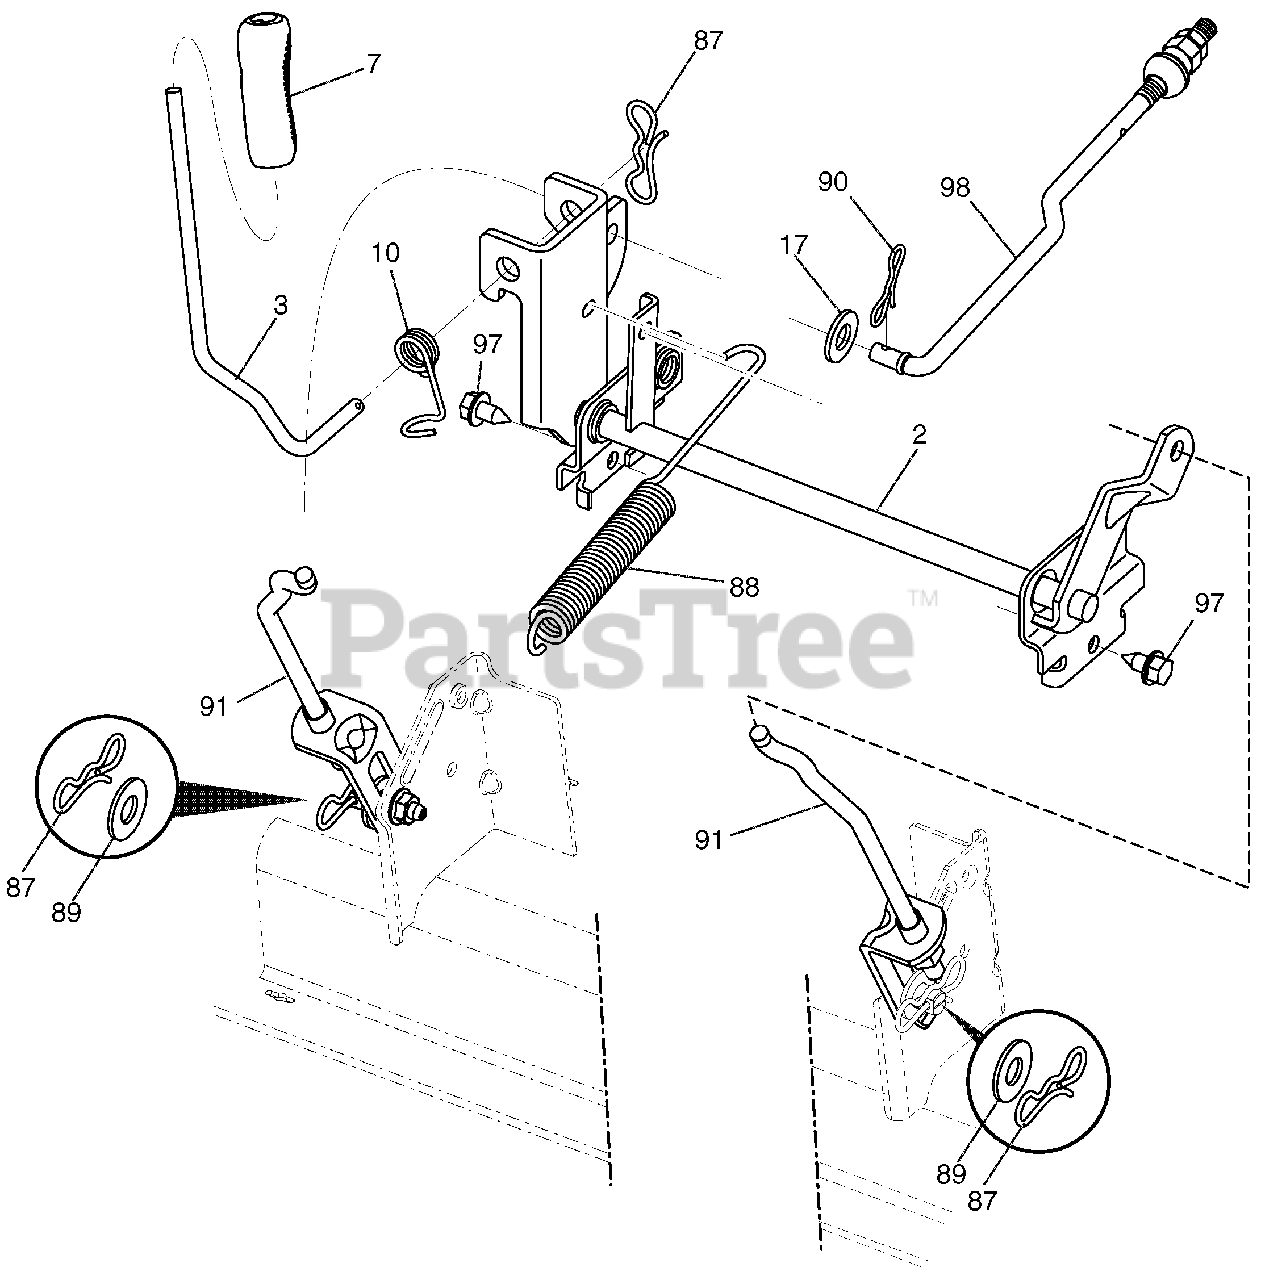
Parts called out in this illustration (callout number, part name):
2	SHAFT ASM., LIFT
3	LEVER.LIFT.HANDLE.LT
7	GRIP LEVER 5625 LD BLACK 428
10	SPRING.TORSION.HANDLE.LIFT
17	Washer 13/32 x 13/16 x 12 Ga.
87	PIN.COTTER.7/16.BOW TIE LOCK
88	SPRING.LIFT ASSIST
89	WASHER.CLEAR ZINC
90	PIN.COTTER.5/16.BOW TIE LOCK
91	LINK.LIFT.SUSP.MOWER.REAR
97	SCREW.HEXWSH THDR3/8-16X3/4.BL
98	LINK.LIFT.SUSP.MOWER.FRONT
